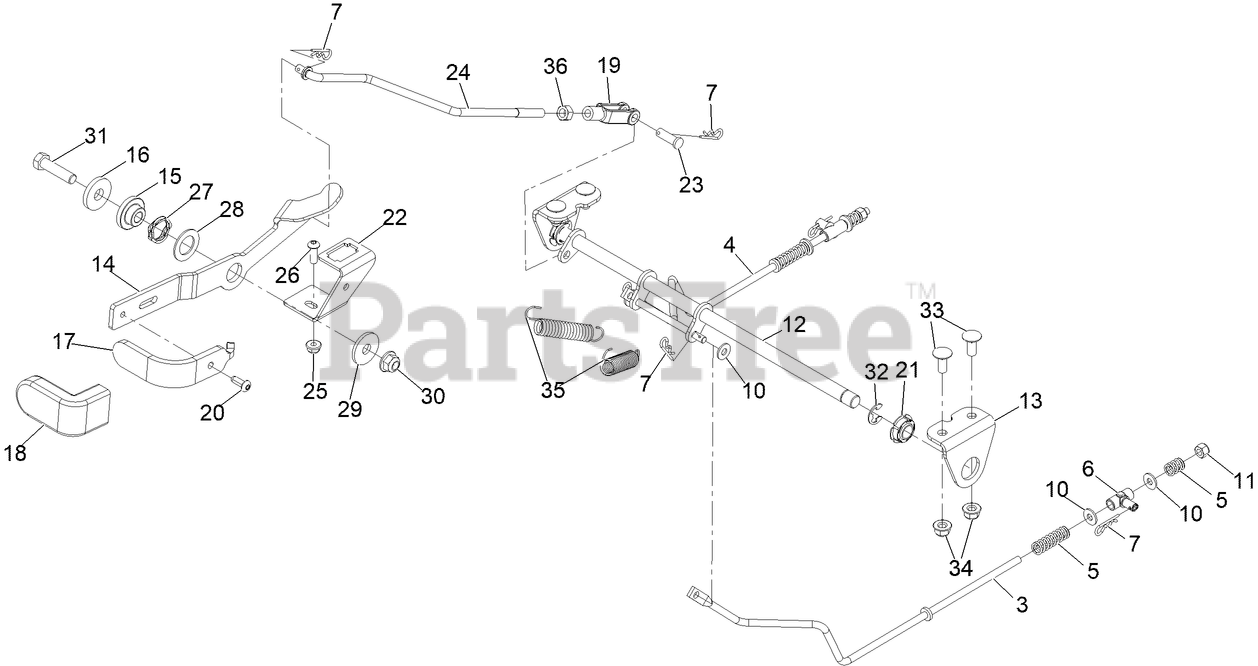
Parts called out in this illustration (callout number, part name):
3	ROD-BRAKE,LH
4	ROD-BRAKE,RH
5	SPRING-COMPRESSION, BAIL
6	MOUNT-PIVOT
11	NUT-LOCK, NI
12	Pivot- Brake
13	ANGLE-MOUNT PIVOT
14	LEVER- BRAKE
15	PIVOT-FLANGE
17	HANDLE-BRAKE
18	GRIP-LEVER
19	YOKE-ADJUSTABLE
21	BEARING-SPHERICAL
22	Bracket- Switch
23	PIN-CLEVIS
24	Rod- Brake
26	SCREW-HSBH
27	WASHER-WAVE
28	WASHER-THRUST
29	WASHER
30	NUT-HF, NI
31	SCREW-HH
32	RING-RETAINING, EXTERNAL
33	SCREW-CARR
34	NUT-HF, NI
35	SPRING-EXTENSION
36	NUT-HEX
